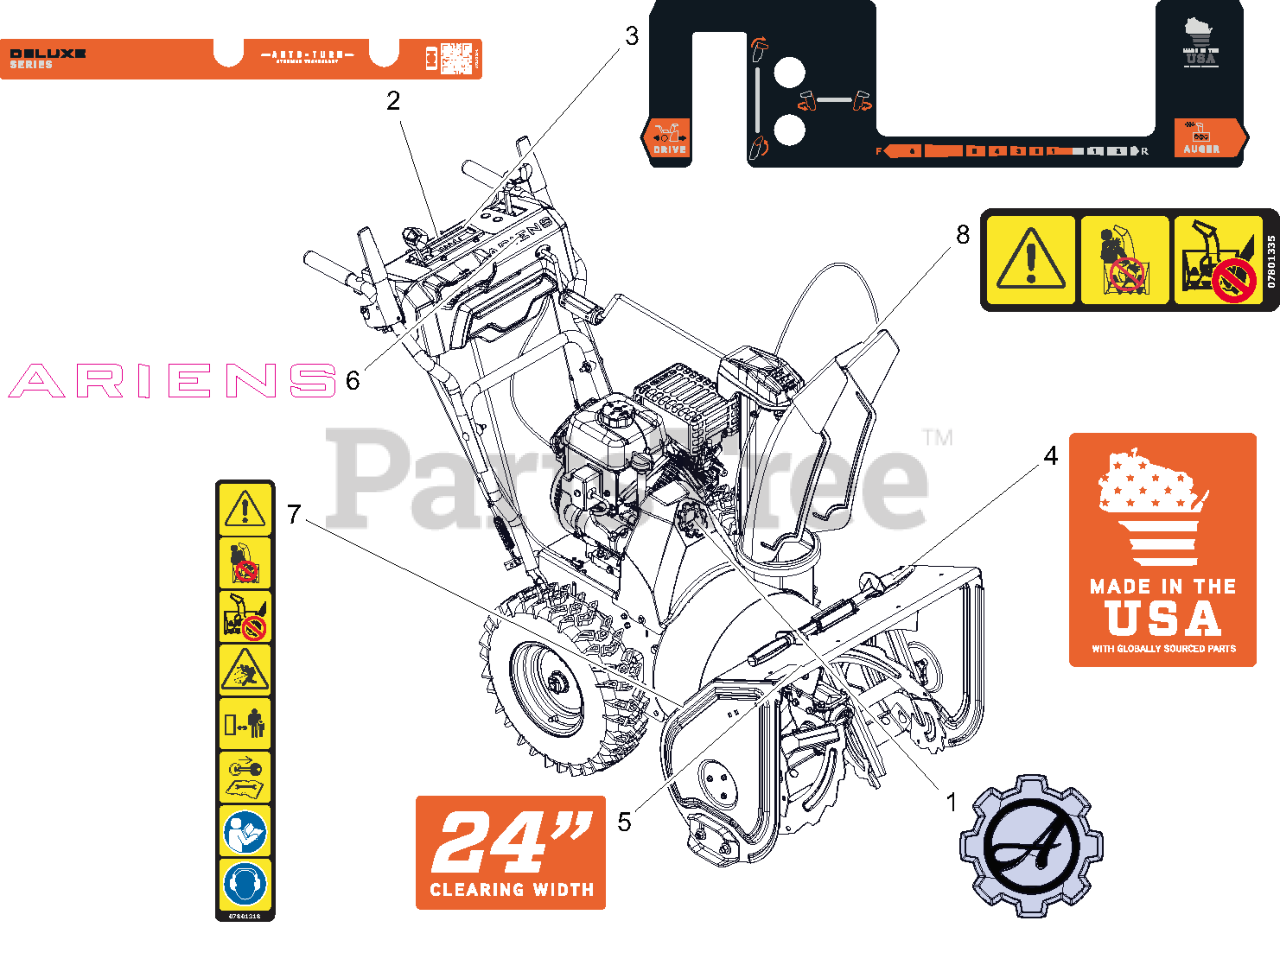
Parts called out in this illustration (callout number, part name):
1	DECAL, ARIENS - GEAR BADGE
2	DECAL- DASH - DELUXE
3	DASH- CONTROL - SMALL DASH
4	DECAL- MADE IN USA
5	DECAL- CLEARING - 24
6	DECAL- ARIENS - 7.46"
7	DECAL- SAFETY - DANGER
8	DECAL- DANGER
